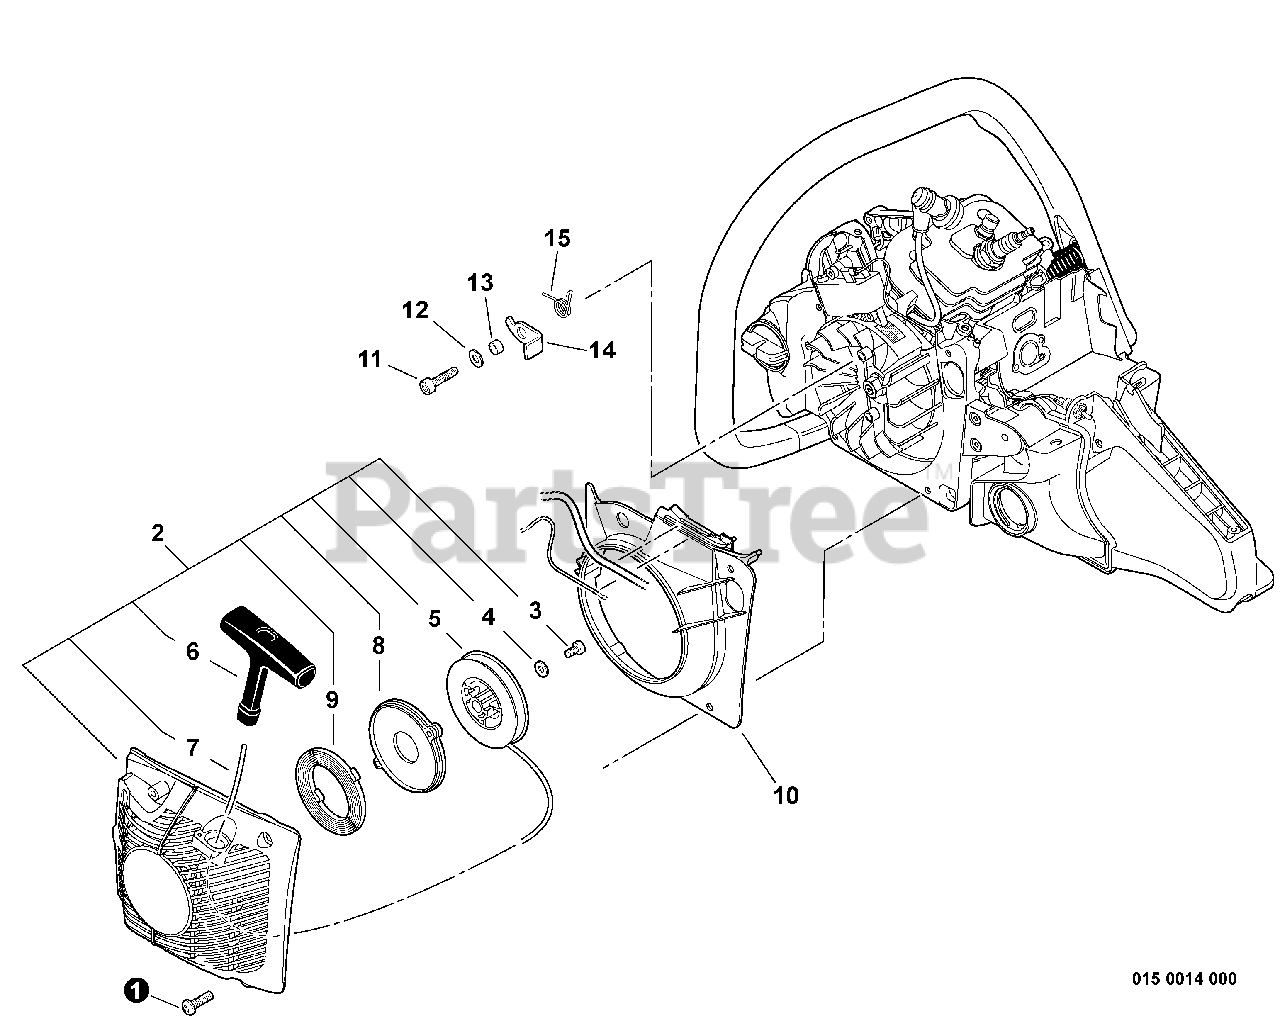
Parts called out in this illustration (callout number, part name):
1	BOLT, TORX 5×20
2	STARTER ASSY, RECOIL
3	BOLT, TORX 5×10
4	WASHER 5.2×16×1.0
5	REEL, ROPE
6	GRIP, STARTER
7	ROPE, STARTER 4.0×950
8	PLATE, STARTER
9	SPRING, RECOIL
10	COVER, FAN
11	BOLT, TORX 5×16
12	WASHER 5.5×12×0.8
13	SPACER 5.2×8×2.1
14	PAWL, STARTER
15	SPRING, TORSION
